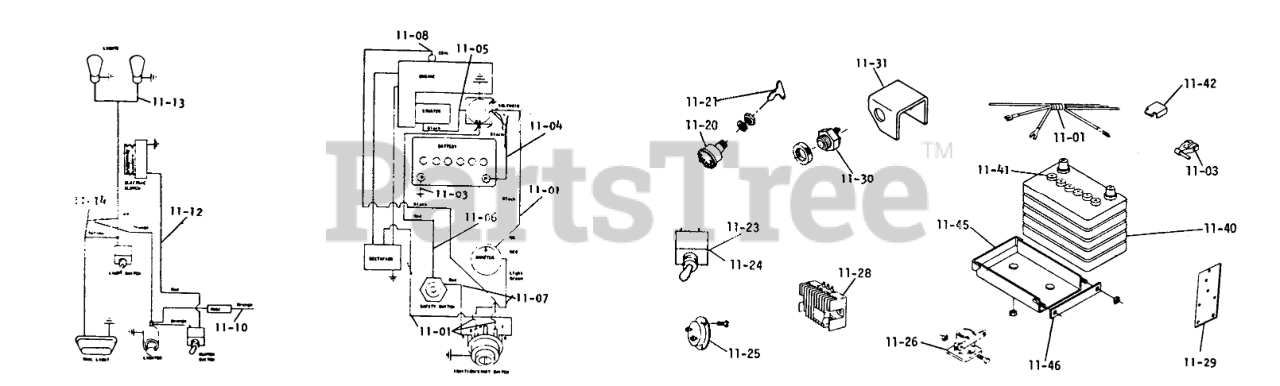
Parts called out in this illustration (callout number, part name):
11-01	Harness-Wiring (Main)
11-01	PLASTIC TIE
11-01	CONTROL PROTECTOR
11-02	Grommet
11-03	Wire-Ground
11-03	WIRE-GROUND
11-03	Wire Assy.-Coil to Harness
11-04	WIRE SOLENOID
11-04	Wire
11-05	Wire
11-06	WIRE ASSY
11-07	Wire Assy.
11-08	Wire Assy.-Coil to Harness
11-10	ASSY FUSED CONNECTOR
11-13	WIRE ASSY
11-14	Harness-Headlights
11-14	CLIP-WIRE
11-20	Switch-Ignition
11-20	Lockwasher 5/8
11-21	Key-EL
11-24	SWITCH-LIGHTS
11-24	Nut, Knurled
11-24	NUT-HEX
11-25	AMMETER W/CLAMP
11-25	Clamp
11-25	HEX NUT 10-32 E.S.
11-26	Solenoid
11-26	Bolt, 1/4-20 Whizlock
11-28	REGULATOR-RECTIFIER
11-28	Bolt 1/4-20 X 3/4
11-28	Nut-Nylok
11-29	PLATE COIL & SOL MTG
11-30	SWITCH SAFETY
11-30	NUT-SPECIAL 9/16-18
11-31	Bracket
11-31	Bolt 3/8-16 x 1
11-40	Battery
11-40	Bolt 1/4-20 X 3/4
11-40	Washer
11-40	Nut-Nylok
11-42	Cover Battery Term
11-45	BATTERY BOX ASSY R (NS)
11-45	Nut-Nylok
11-45	Battery Box
11-46	LINK BATTERY CLAMP
11-46	Nut-Nylok
11-46	LINK BATTERY CLAM R
